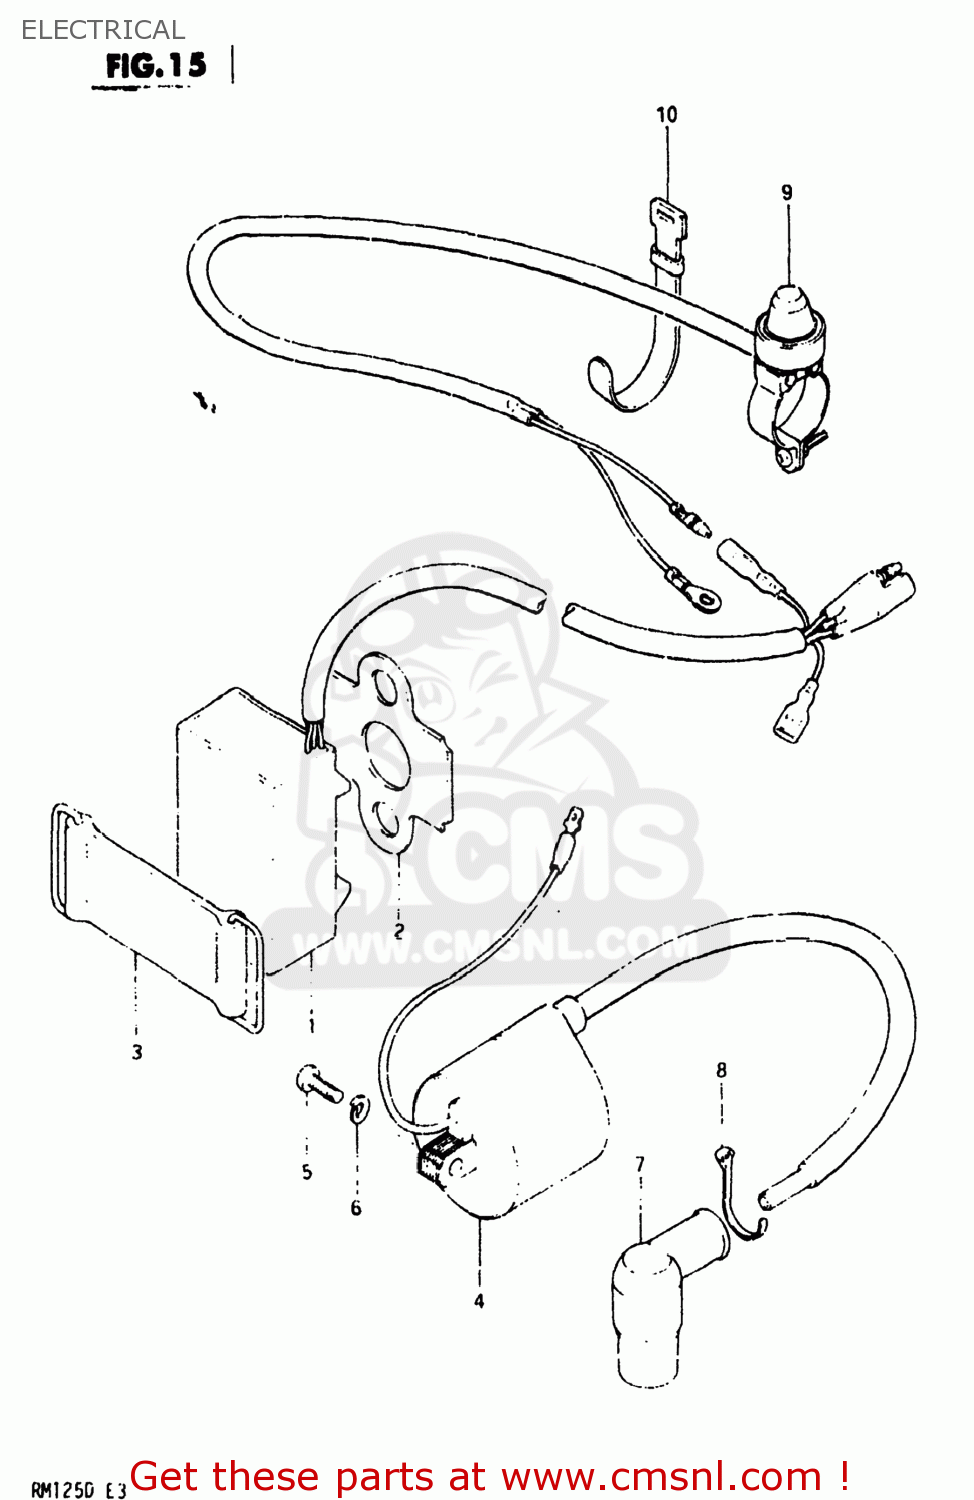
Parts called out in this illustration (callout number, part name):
1	CDI UNIT
2	PROTECTOR,CDI UNIT
3	BAND
4	COIL ASSEMBLY,IGNITION
5	SCREW
6	LOCK WASHER
7	CAP,SPARK PLUG
8	CLAMP
9	SWITCH ASSEMBLY
10	CLAMP(L:120)
